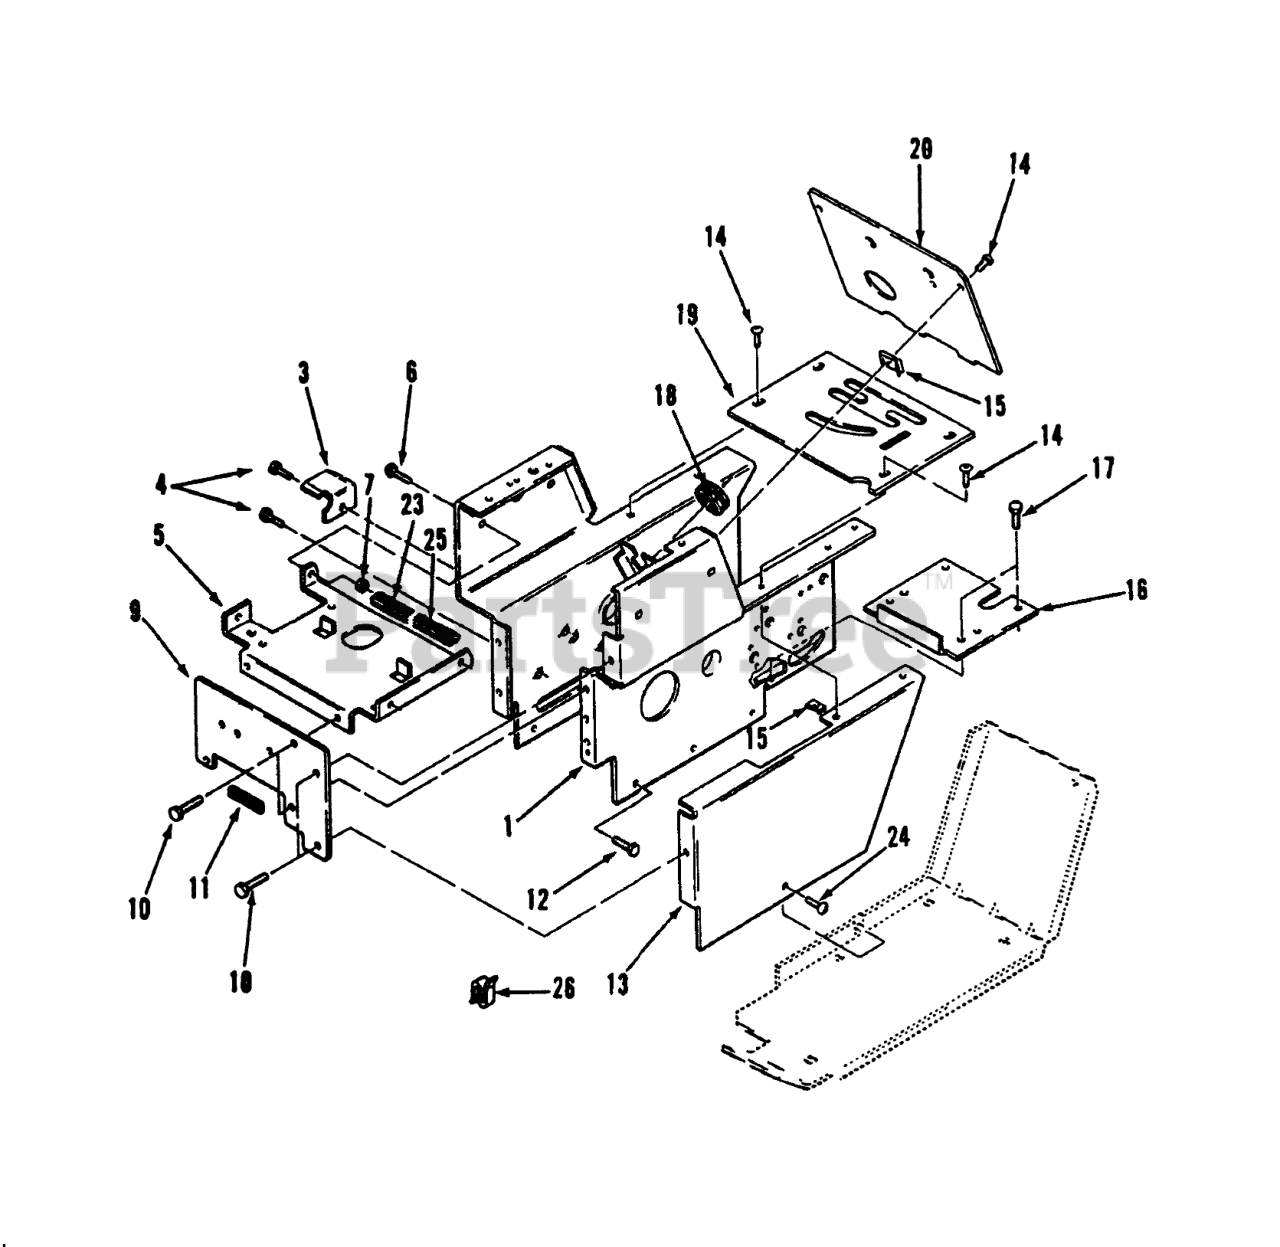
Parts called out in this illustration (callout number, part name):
1	Handstand
3	Belt Bracket
4	SCREW
5	SUPORT-BATERYB
6	BOLT CARR. 5/16X1/2 BK
7	NUT-HEX
9	Front Plate
10	SCREW
11	EDGE TRIM 4IN OF 102896
12	SCREW
13	Cover-Side LH
14	Screw
16	Cover-Dust
17	SCREW
18	GROMMET
19	Plate-Shift Cover
20	Plate-Hood Stand
23	EDGE TRIM 5" OF 102896
24	Screw
25	EDGE TRIM 2" 102896
26	SPEED CLIP
